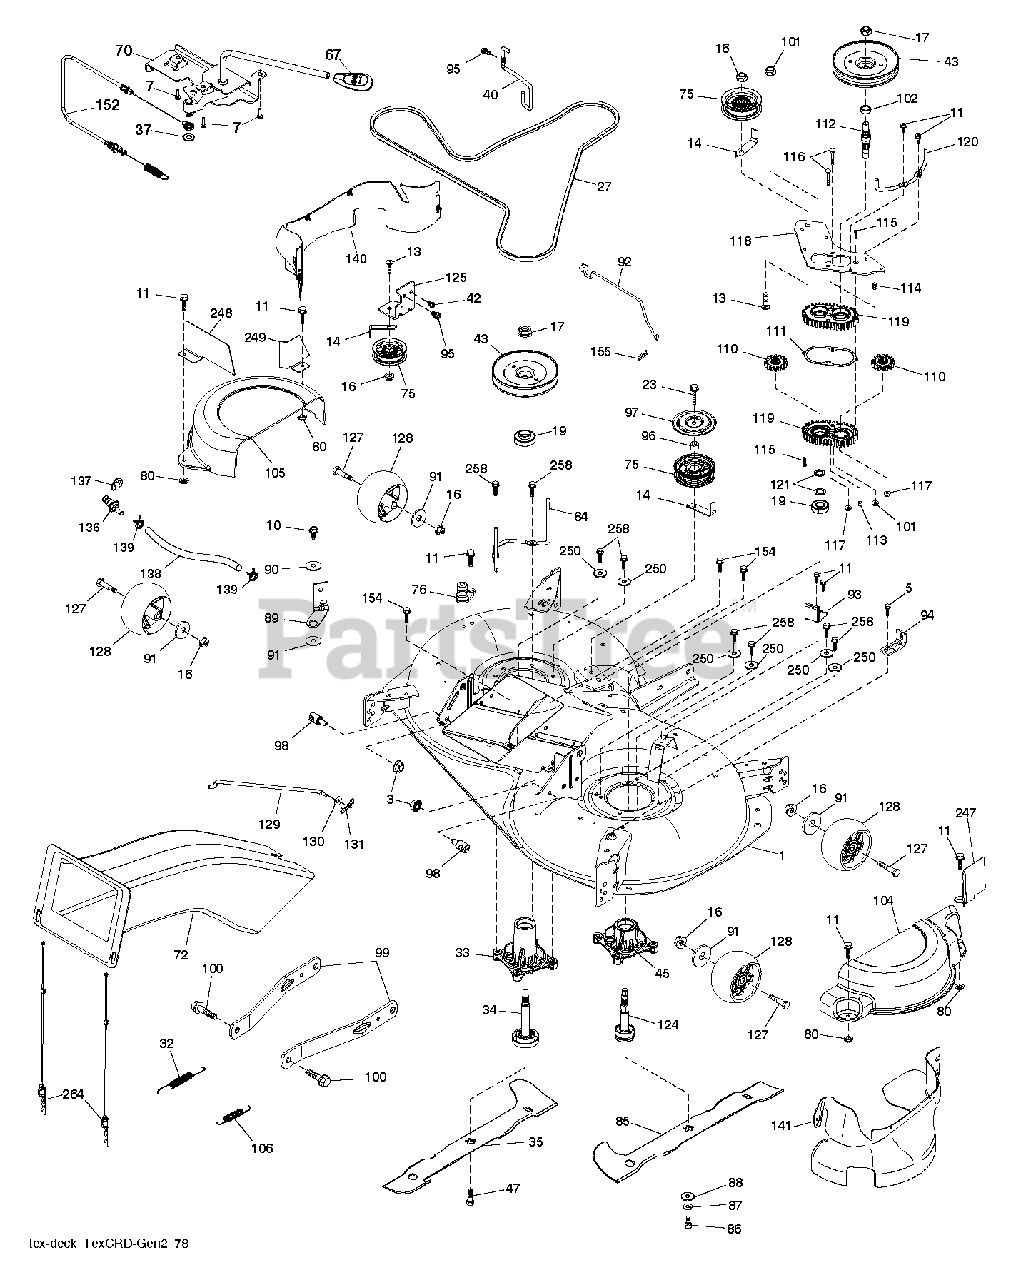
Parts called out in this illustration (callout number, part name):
1	DECK SVCX.107HP.C.BL.498
3	NUT LOCK HEX FLANGE 5/16-18
5	BOLT.5/16HEX.WHS.HD
7	SCREW.#10 X 0.750.BOS
10	SCREW 3/8-16X1
11	SCREW.1/4-20X5/8
13	BOLT.3/8-16X1.50
14	KEEPER, BELT IDLER
16	NUT LOCK FLG 3/8-16 UNC
17	NUT.FLANGE.LOCK.TOP
19	BEARING.MANDREL.TOP.EXTENDED
23	SCREW LT
27	BELT BELT. MOWER DRIVE 97.4 EL
32	SPRING RETURN
33	HOUSING.MANDREL.REV.TALL.N/GRS
34	SHAFT ASM.REV.TALL.N/GREASEBL
35	BLADE.107.LH.SINGLE.NON.QD
37	WASHER
40	KEEPER BELT ENGINE LH
42	SCREW
43	PULLEY PULLEY MANDREL 5.438 PD
45	RP HOUSING.MANDREL.REV.REVS.
47	SCREW.SEMS.7/16-20X1.HEX.HEAD
67	HANDLE.CLUTCH.CABLE.LT
70	CLUTCH.ASM.MANUAL.YT.PREDATORQ
72	RB CHUTE 107/97 TEX GENII
75	FLAT IDLER PULLEY
76	1/2" BARB.DECK.WASHOUT.PORT
80	PALNUT 1/4
84	KEEPER KEEPER. LH MANDREL BELT
85	BLADE.107.RH.SINGLE.NON.QD
86	BOLT.3/8-24X1.25GR8. LHTHRD
87	LOCKWASHER
88	WASHER.BLADE
89	ARM BRAKE MOWER
90	SPACER.RETAINER
91	WASHER
92	ROD ASM BRAKE ROD 107 TEX CRD
93	ARM.BRAKE.97.RH
94	BRKT.CLUTCH.CABLE
95	SCREW, 3/8-16X3/4
96	SPACER
97	PROTECTOR
98	STUD.FASTNER.W/ANTI-ROTATE
99	ARM.SUSPENSION.MOWER.R
100	BOLT.SHOULDER
101	NUT.CROWNLOCK.9/16 -18.UNC
102	SPACER BEARING
104	COVER.MANDREL.107.RH.GEN.2
105	COVER.MANDREL.107.LH.GEN.2
106	SPRING.BRAKE.RETURN.38"
110	CRD.SPUR.GEAR
111	GASKET GASKET GEARCASE
112	SHAFT SHAFT. CRD GEARCASE ADAP
113	PLUG PLUG OIL
114	VENT.BREATHER.1/8 NPT
115	SCREW
116	BOLT.CARIGE.SS.1/4-20X1.75GR5
117	NUT T
118	ARM ARM. CLUTCHING 107 TEX CRD
119	GEARCASE GEARCASE SUBASM
120	KEEPER KEEPER. RH MANDREL BELT
121	WASHER WASHER
124	SUB.ASM.REVERSE.THREAD.REV
125	BRACKET BRACKET IDLER CHASSES
127	BOLT.SHOULDER.3/8-16X3-5/8.
128	WHEEL. GUAGE RALLY
129	ROD ROD. SWAY CRD GEN II
130	WASHER
131	PIN.COTTER.5/16.BOW TI
136	PLUG WASHOUT PORT HOOKUP
138	107.WASHOUT.PORT.HOSE (2 2)
139	HOSE.3/8.CLAMP (2 2)
140	GUARD.ASSEMBLY.107.LH.FRENCH
141	GUARD.ASSEMBLY.107.RH.FRENCH
152	CABLE CABLE CLUTCH ASSEMBLY
154	SCREW T-30 1/4-20 X
155	RETAINER M
247	GUARD.STEEL.CRD.MANDREL.COV.FR
248	GUARD.STEEL.CRD.MANDREL.COV.FR
249	GUARD.STEEL.CRD.MANDREL.COV.FR
258	BOLT.HEX.WASHR.HED.313-18X1.19
264	RETAINER.ASM.UPPERCHU
